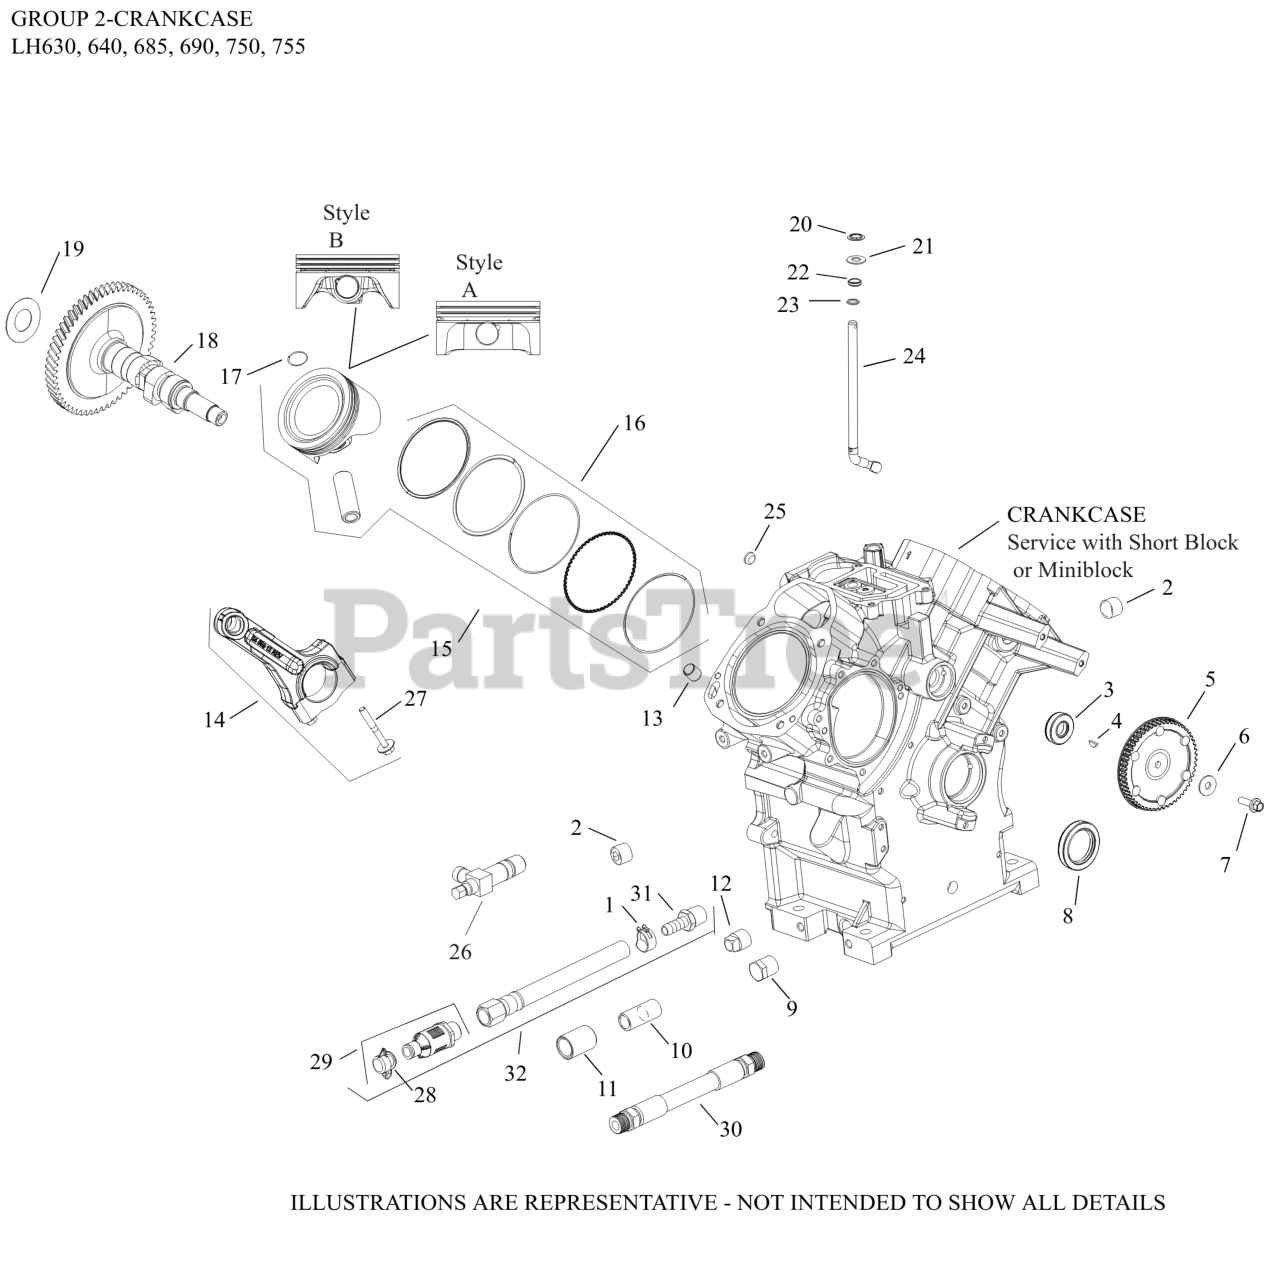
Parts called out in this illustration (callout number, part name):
2	PLUG, PIPE CTSK 3/8"
3	SEAL, CAMSHAFT
4	KEY, 3/32" X 3/8"
5	SPROCKET, CAMSHAFT
6	WASHER, FLAT 1/4"
7	SCREW, FLG M6x1.0x20
8	SEAL, OIL (HELIX LIP)
13	PIN, LOCATING
14	ROD, ASSY CON (STD)-USE 24 067 30-S
14	ROD, ASSY CON(.25mm) -USE 24 067 31-S
15	KIT,PISTON (STD) STYLE A -(#2487454S)
15	KIT,PISTON (.08) STYLE A-USE 24 874 55-S
15	KIT,PISTON (.25) STYLE A - (#2487456S)
15	KIT, PISTON (.50) STYLE A
15	KIT, PISTON (STD) STYLE B
15	KIT, PISTON (.08) STYLE B-(#DSC)
15	KIT, PISTON (.25) STYLE B
15	KIT, PISTON (.50) STYLE B
16	USE PISTON ASSY PER SPEC - DISC
16	RING SET (.08) STYLE A - (#DSC)
16	RING SET (.25) STYLE A - DISC
16	RING SET (.50)STYLE A-(#2410829S)
16	RING SET (STD) STYLE B
16	RING SET (.08) STYLE B
16	RING SET (.25) STYLE B
16	RING SET (.50) STYLE B
17	RETAINER, PISTON PIN
18	KIT, CAMSHAFT
19	SHIM, CAMSHAFT (WHITE .028")
19	SHIM, CAMSHAFT (BLUE .03")
19	SHIM, CAMSHAFT (RED .032")
19	SHIM, CAMSHAFT (YELLOW .034")
19	SHIM, CAMSHAFT (GREEN .036")
19	SHIM, CAMSHAFT (GRAY .038")
19	SHIM, CAMSHAFT (BLACK .04")
20	RETAINER, RING
21	WASHER, FLAT 9 MM
22	SEAL, GOVERNOR CROSS SHAFT
23	WASHER, FLAT 11/32"
24	SHAFT, GOVERNOR CROSS
27	KIT, ROD BOLTS-(#25086677S)
27	KIT, ROD BOLTS
